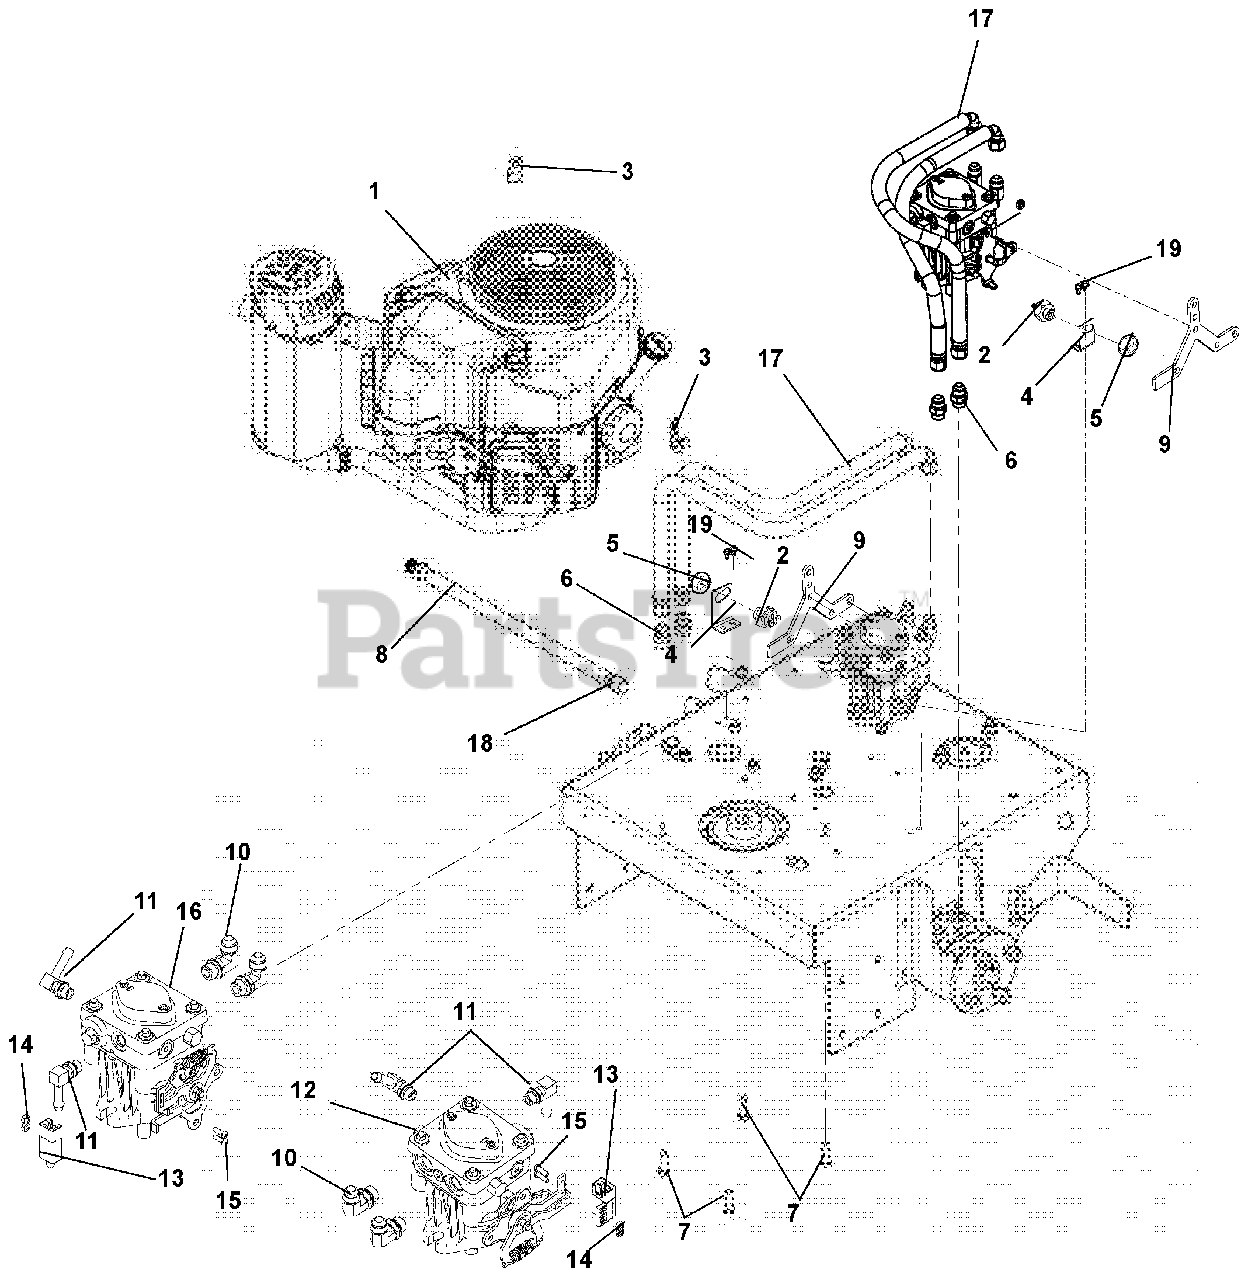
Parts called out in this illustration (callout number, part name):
1	ENGINE, KAWASAKI FS600 (988324, 988325)
1	ENGINE, KAWASAKI FS481 (988323)
2	SWITCH-NEUTRAL START N.O.
3	P-CLIP, .500 INSULATED
4	BRACKET, SWITCH MOUNTING
5	NUT-STAMPED .56-18
6	FITTING, STRAIGHT
7	BLT-HEX.38-16X1.25FTHG5 EP80YZ
8	OIL DRAIN, M20
9	BRACKET, PUMP
10	FTG, ADP JIC-ORB 6801-08-08
11	FTG, 90 9/16 MOR X 3/8 HOSE
12	PUMP, LH HYD PE (10cc)
13	SWITCH, PLUNGER DP - N.O. - N.C.
14	LOCKNUT, 10-24 NYLOC Y
15	SCREW, 10-24X.625 PAN PHL MACY
16	PUMP, RH HYD PE (10cc)
17	HOSE, HYD 1/2 X 26 1/2 EZFLEX
18	PIPE CAP 3/8 NPT FEMALE
19	SCR-TAP .25-20 X .5 HWH TR YWZ
